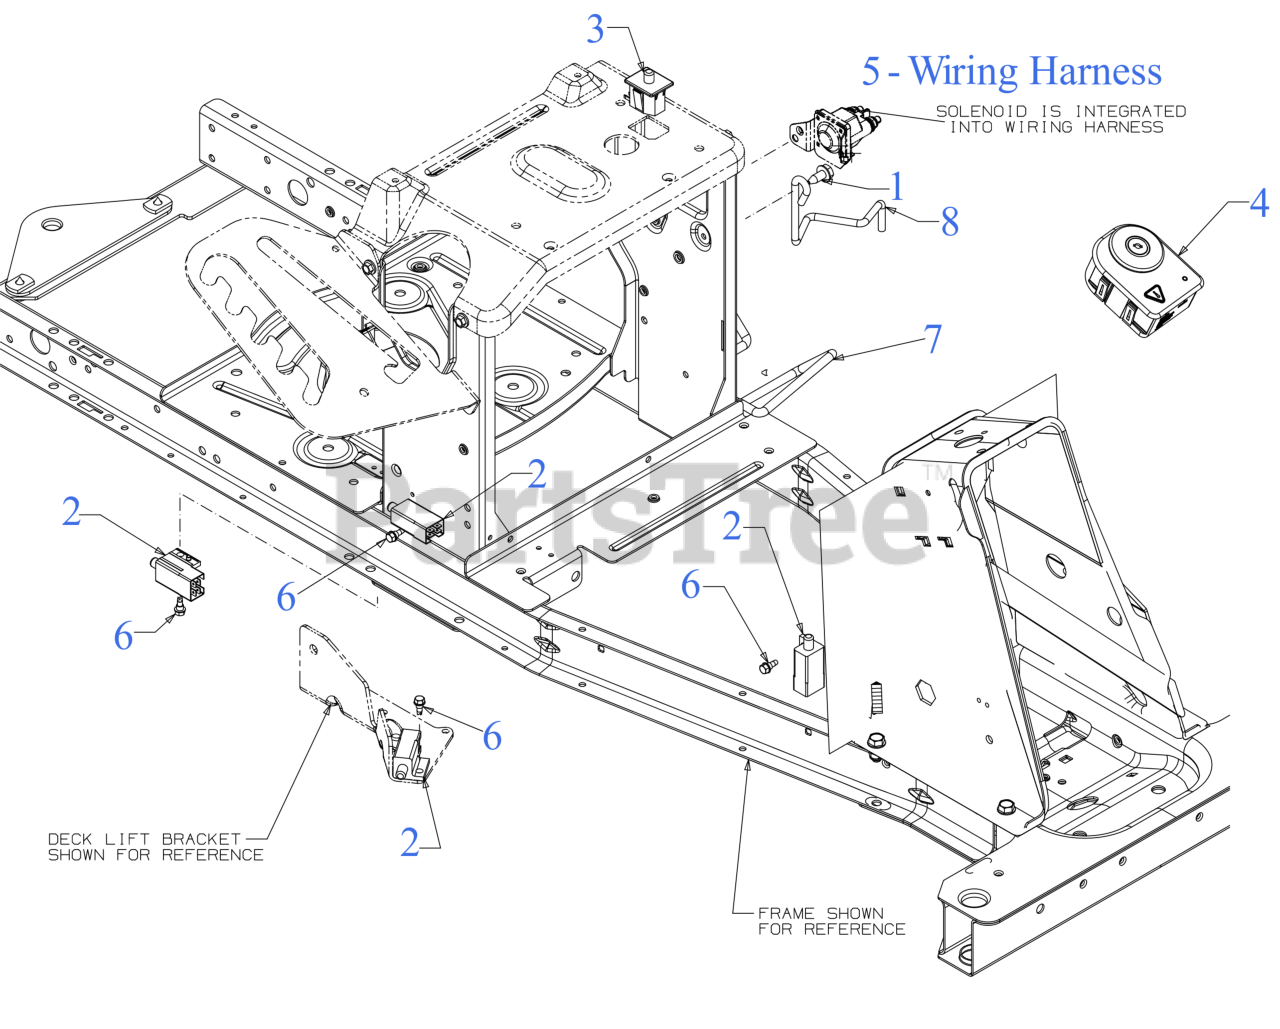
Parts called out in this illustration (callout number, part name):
1	SCREW 5/16-18 x .750
2	INTERLOCK SWITCH (NO/NC)
3	SEAT SWITCH N/C,N/C
4	IGNITION MODULE SWITCH RMC (MAN PTO BLK)
5	HARNESS (RMC SOL HYDRO HDLT)
5	12V SOLENOID
6	SHOULDER SCREW
7	BATTERY TRAY ROD
8	BATTERY HOLD DOWN ROD
